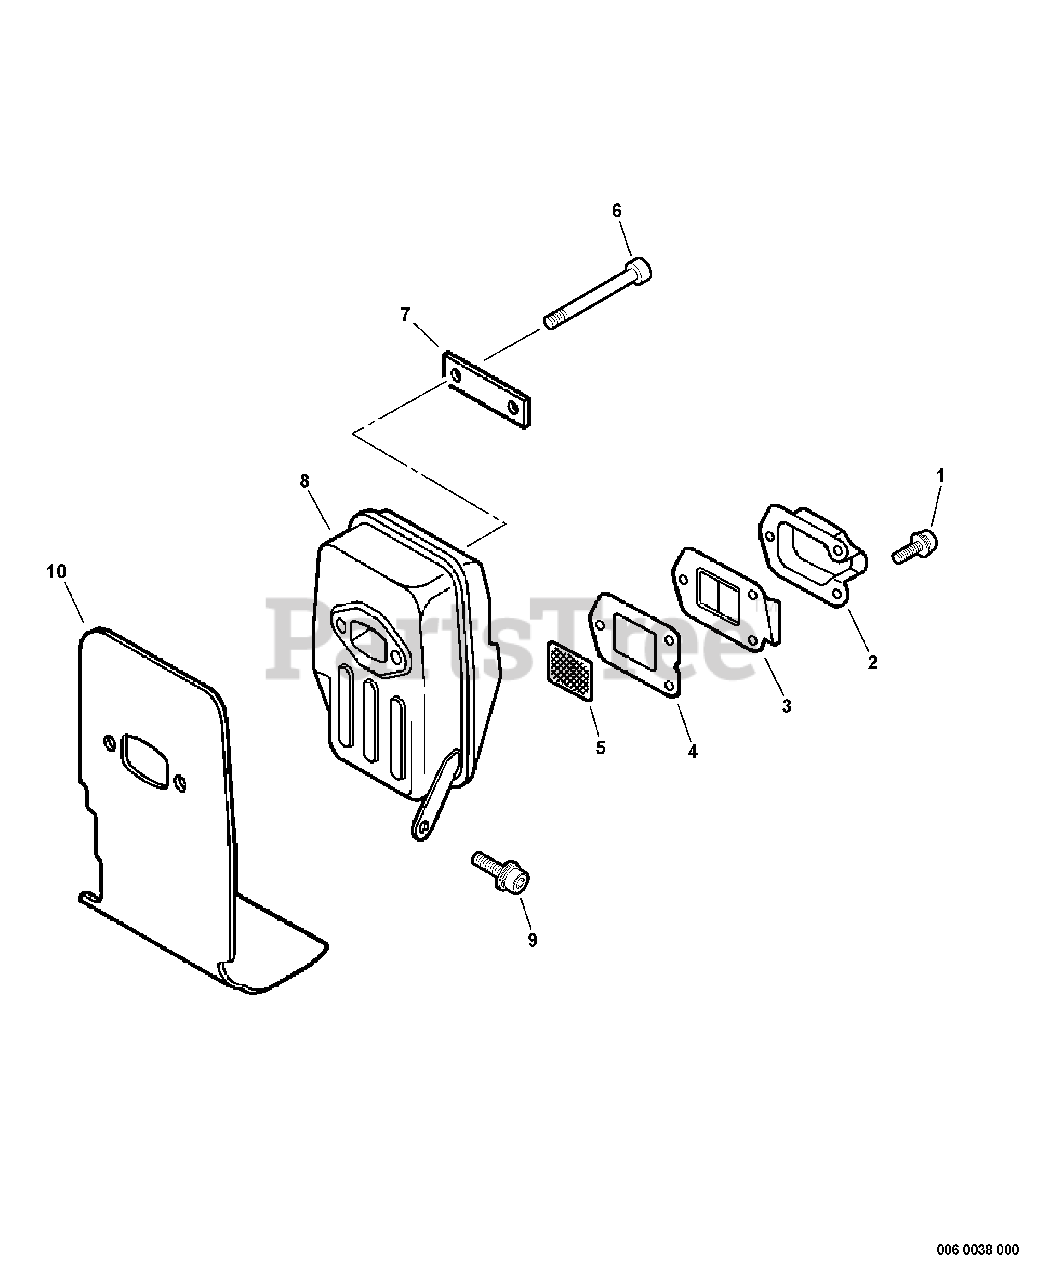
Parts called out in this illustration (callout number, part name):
1	SCREW - 4X10
2	GUIDE, EXHAUST - OUTER
3	GUIDE, EXHAUST - INNER
4	GASKET, EXHAUST
5	SCREEN, SPARK ARRESTOR
6	SCREW - 6X60
8	MUFFLER
9	SCREW - 5X12
10	SHIELD, EXHAUST
